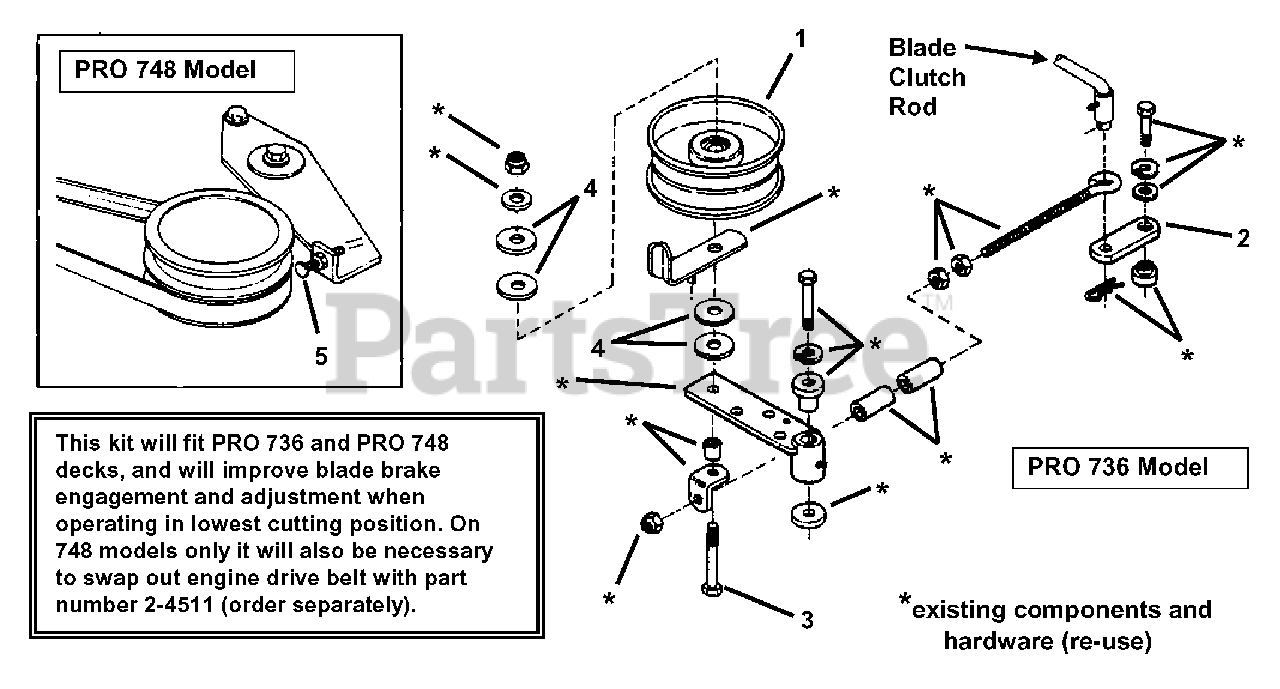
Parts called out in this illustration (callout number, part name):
1	PULLEY, 5" Idler
2	LINK, Blade Assist
3	BOLT, 3/8-16 x 3" Hex, Grade 5
4	WASHER, Flat (Case Hardened)
5	BOLT, 5/16-18 x 1-3/4" Square Neck Carriage, Grade 2
24511	BELT
